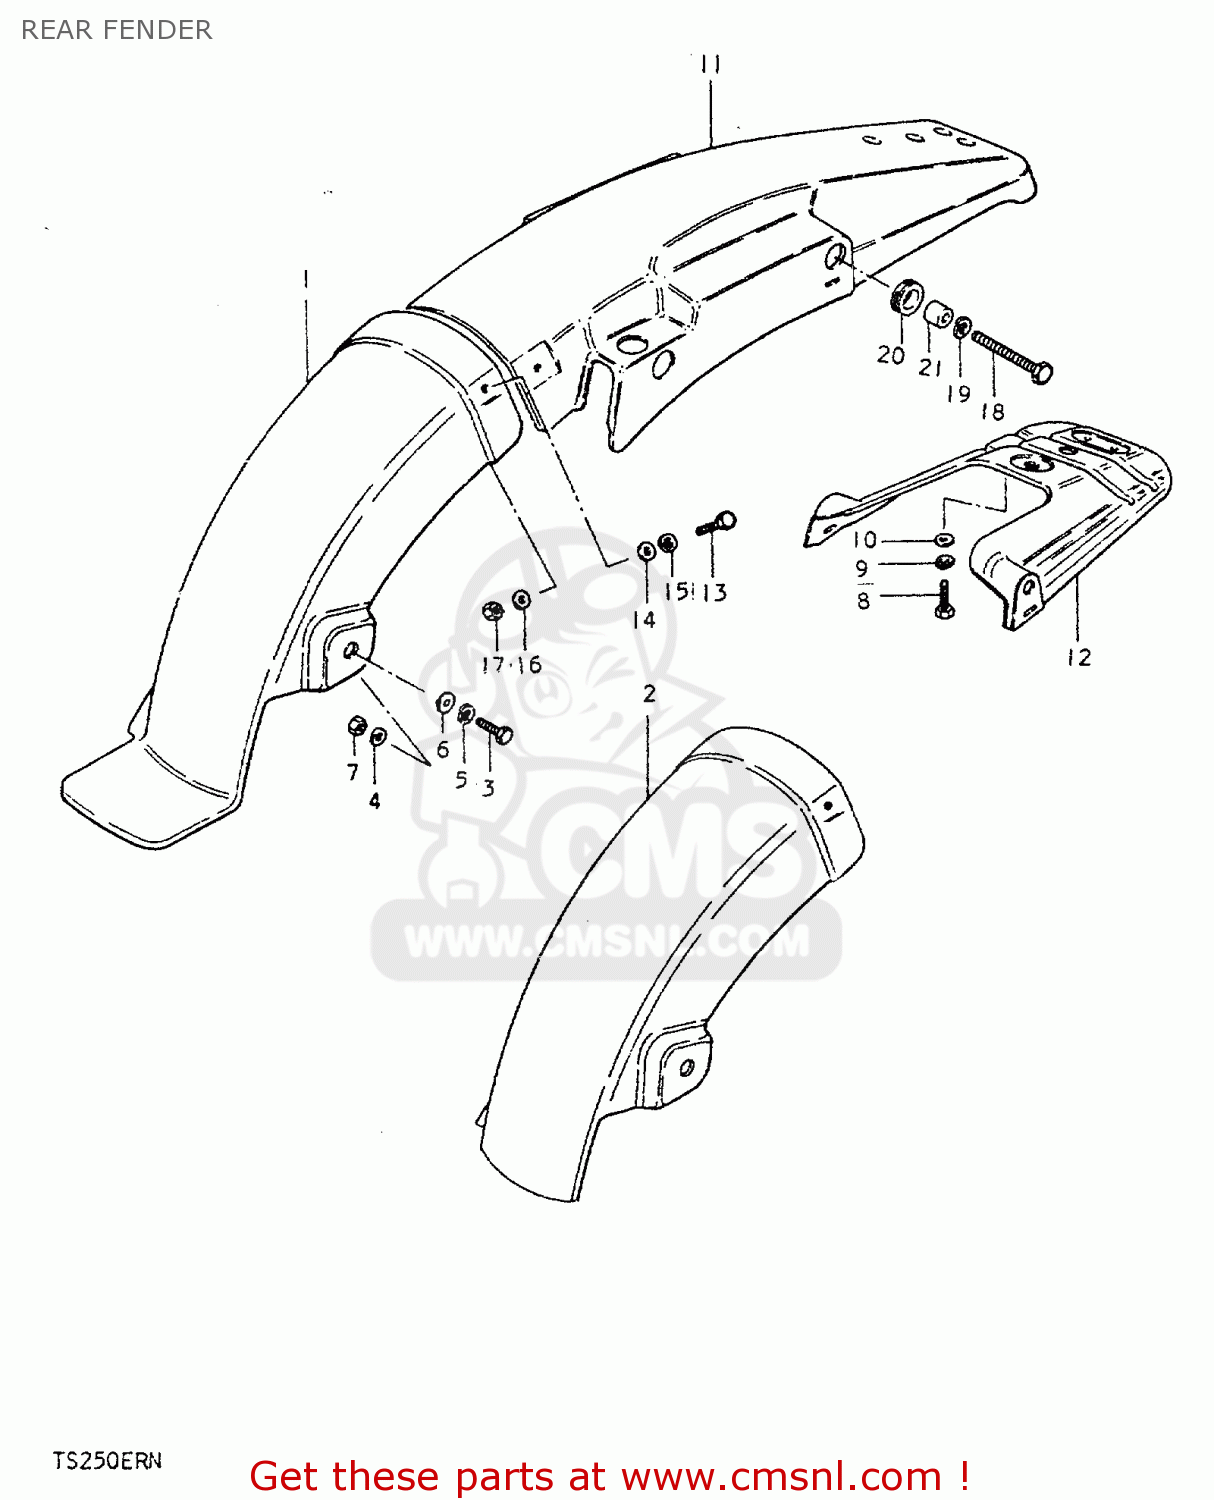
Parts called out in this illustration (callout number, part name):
1	FENDER,REAR
3	BOLT, UPPER
4	WASHER
5	LOCK WASHER
6	WASHER
7	NUT
8	BOLT
9	LOCK WASHER
10	WASHER
11	FENDER, REAR
12	REINFORCEMENT,REAR FENDER
13	BOLT
14	WASHER (5.5X16X1.2)
15	LOCK WASHER
16	WASHER(5.2X16X1)
17	NUT
18	BOLT (8X30)
19	LOCK WASHER
20	CUSHION
21	SPACER (8.2X12X7.5)
